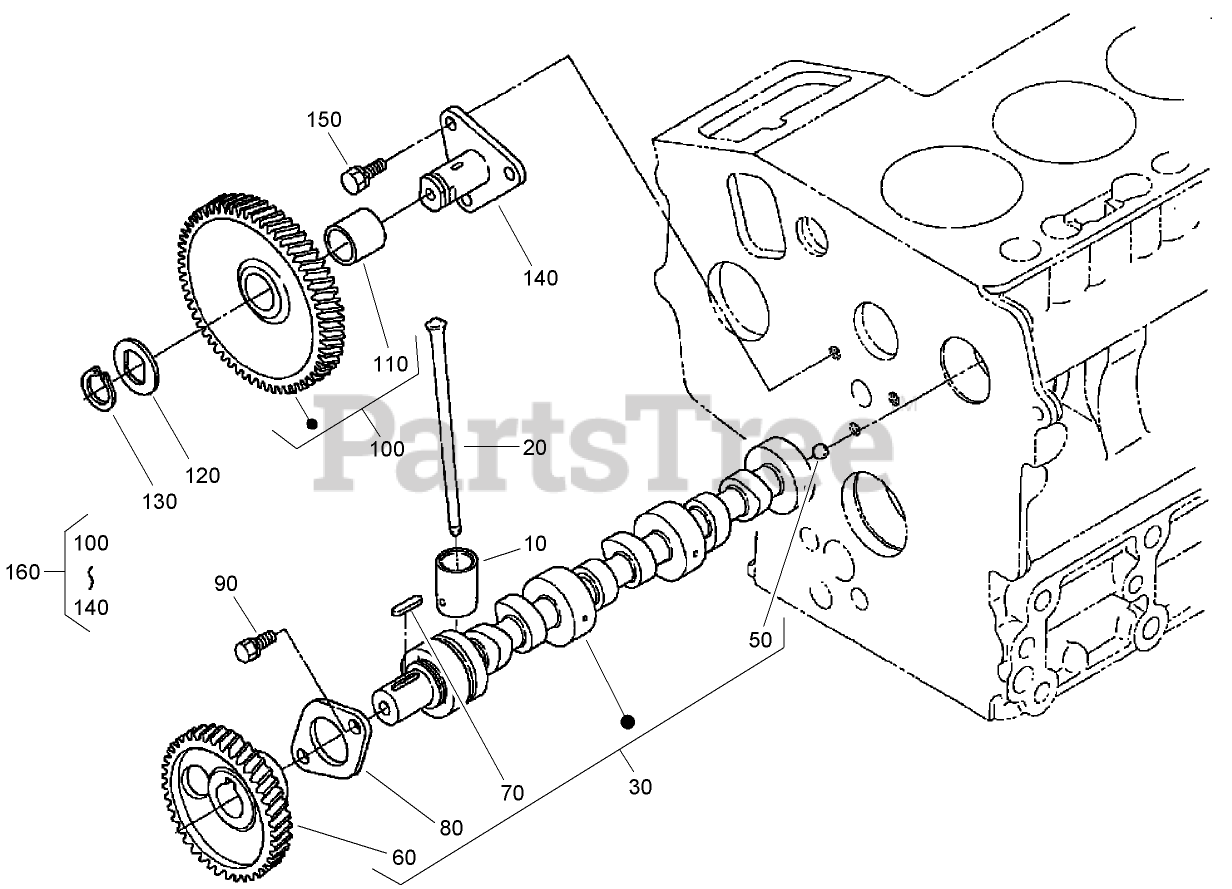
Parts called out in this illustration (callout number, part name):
10	TAPPET
20	ROD-PUSH
30	CAMSHAFT ASM
60	GEAR-CAM
70	KEY-FEATHER
80	STOPPER-CAMSHAFT
100	GEAR-IDLE
110	BUSHING
120	COLLAR-GEAR, IDLE
130	RING-SNAP
140	SHAFT-GEAR, IDLE
160	IDLE GEAR ASM
